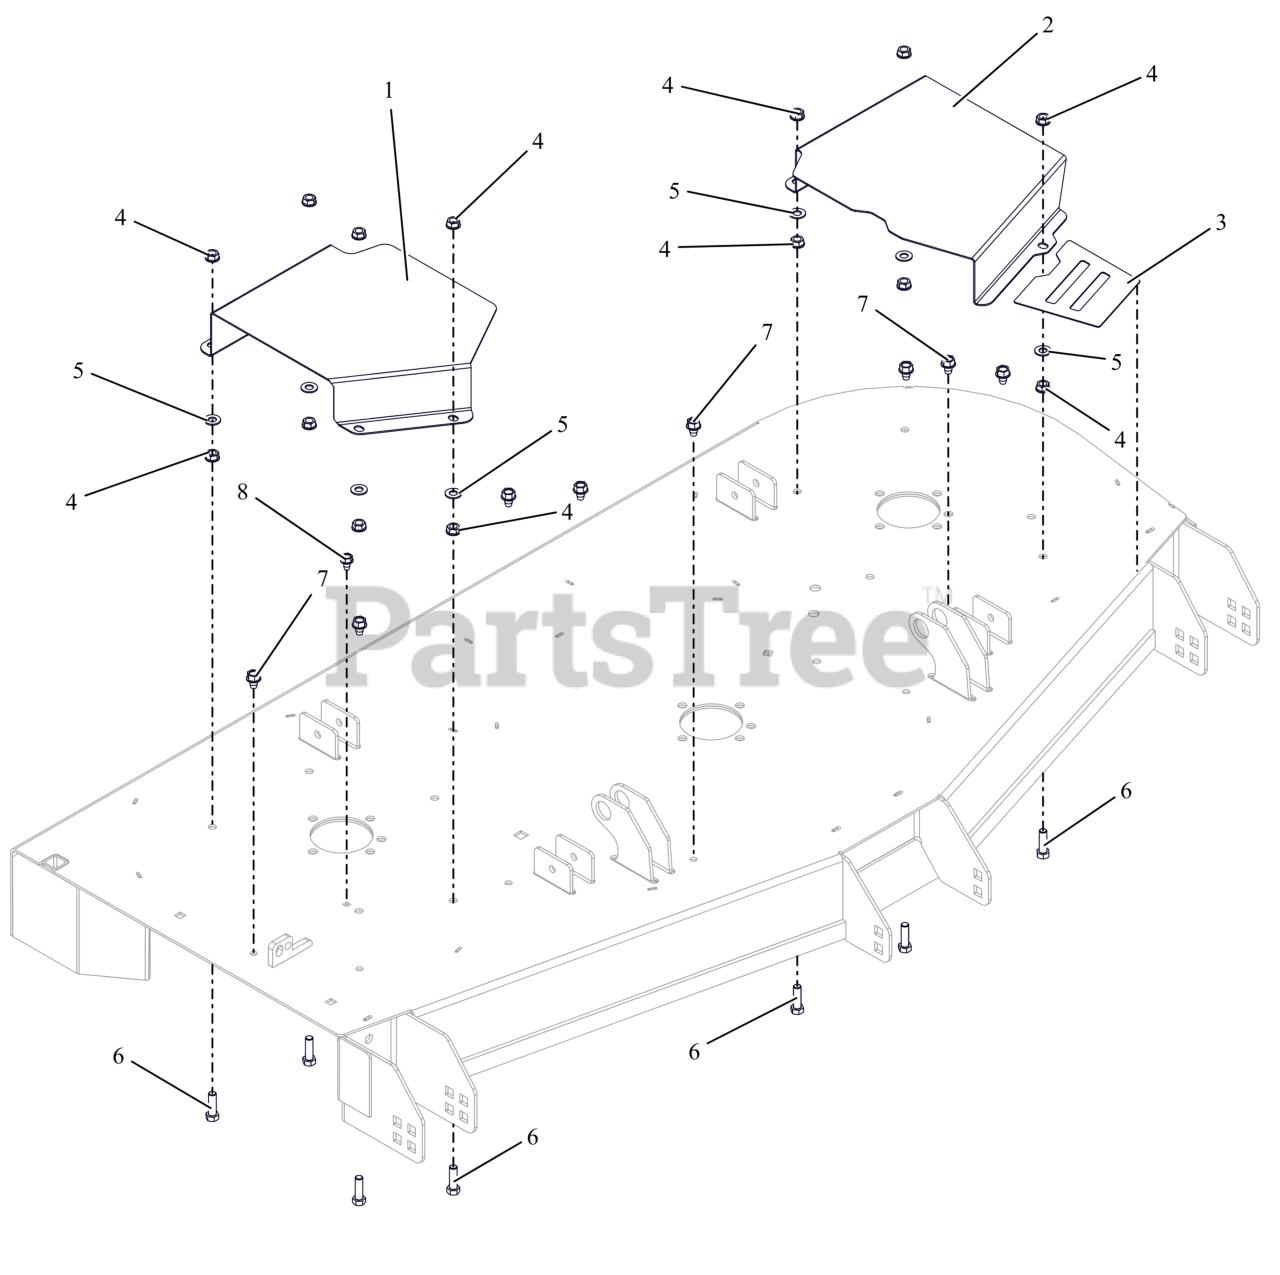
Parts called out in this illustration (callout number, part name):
1	COVER- BELT 52/60" RIGHT
2	COVER- BELT 60" LEFT
3	GRIP TAPE 52-60 BELT COVER
4	NUT, SPNLK-FLG .38-16 G5 ZCC
5	WSHR,FLT .406X.812X.065 ZCC
6	BLT, HEX .38-16X1.25 G5 ZCC
7	SCR,TAP .375-16X.50 HWH TR ZCC
8	SCR,TAP .312-18X.50 HWH TR ZCC
